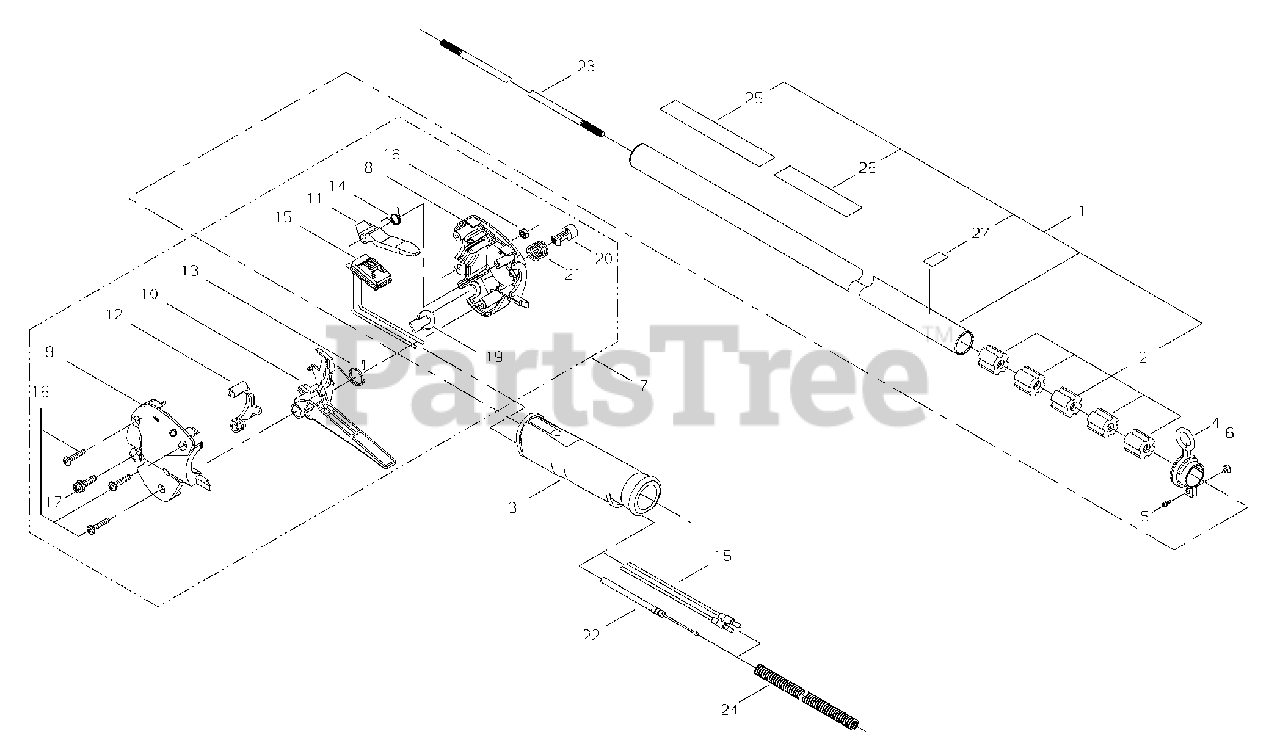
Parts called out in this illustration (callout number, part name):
1	MAIN PIPE ASSY
2	BUSHING
4	HANGER, SWIVEL
5	BOLT M5×12
6	NUT M5
7	THROTTLE CONTROL ASSY
8	CONTROL HANDLE - RIGHT
9	CONTROL HANDLE - LEFT
10	TRIGGER, THROTTLE
11	LEVER, THROTTLE LOCKOUT
12	LOCKOUT, THROTTLE
13	SPRING, THROTTLE RETURN
14	SPRING, THROTTLE LOCKOUT
15	SWITCH, ON-OFF
16	SCREW, TAPPING M4×20
17	SCREW M5×20
18	NUT M5
19	PLUG
20	BUTTON, THROTTLE LOCK
21	SPRING, COMPRESSION
22	CABLE, THROTTLE
23	MAINSHAFT
24	TUBE, PLASTIC PROTECTIVE
25	LABEL, SHINDAIWA PROFESSIONAL
26	LABEL, CAUTION (BLADE CAPABLE)
27	LABEL - CAUTION
